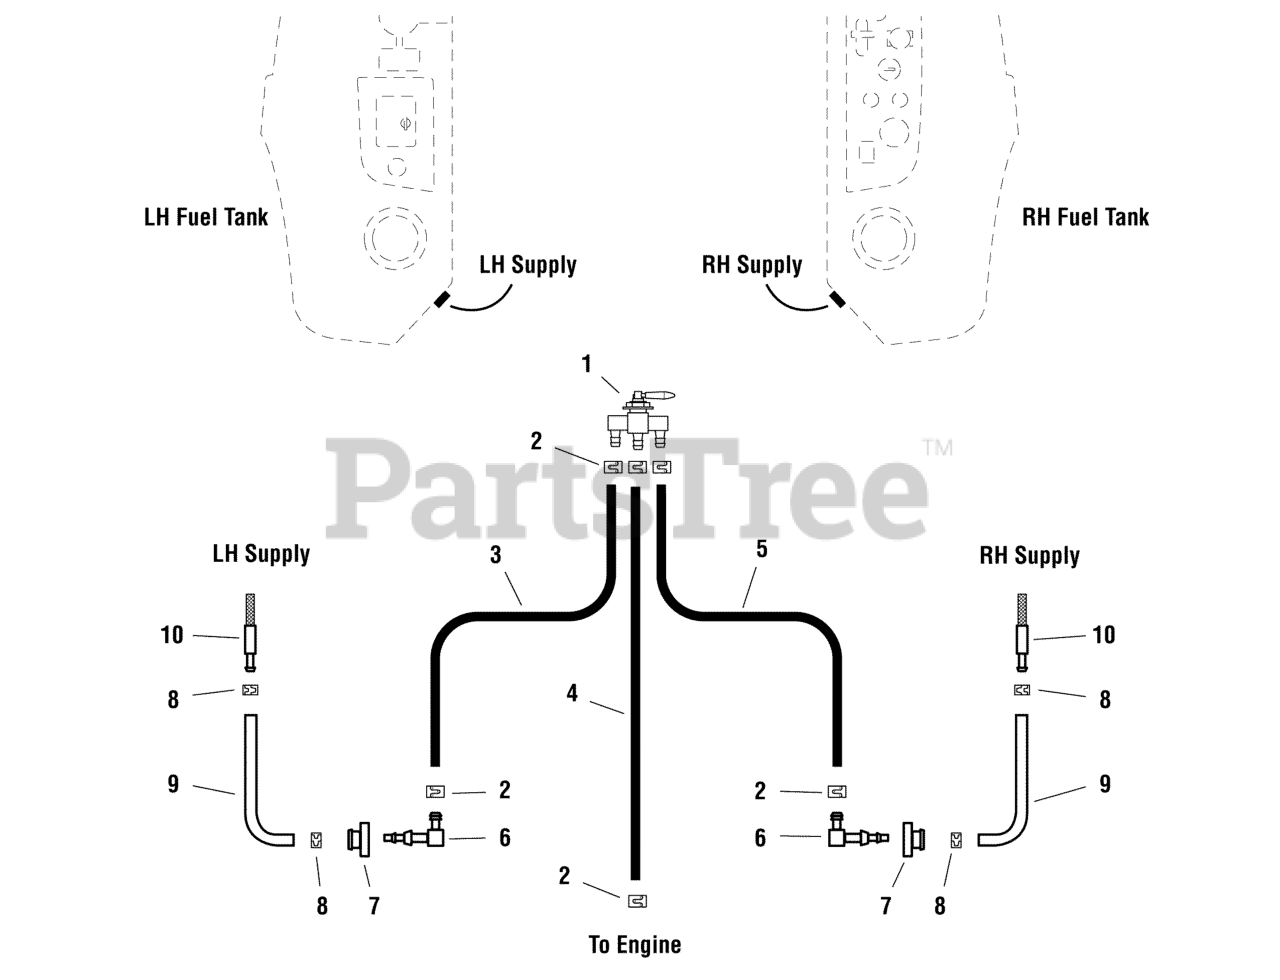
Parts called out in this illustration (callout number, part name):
1	VALVE, Fuel Shut Off
2	CLAMP, Hose
3	HOSE, 1/4 FUEL, 50"
4	HOSE, 1/4" FUEL, 47.00"
5	HOSE, 1/4 FUEL, 72"
7	BUSHING-FUEL TANK RED RUBBER
9	HOSE ASSEMBLY
